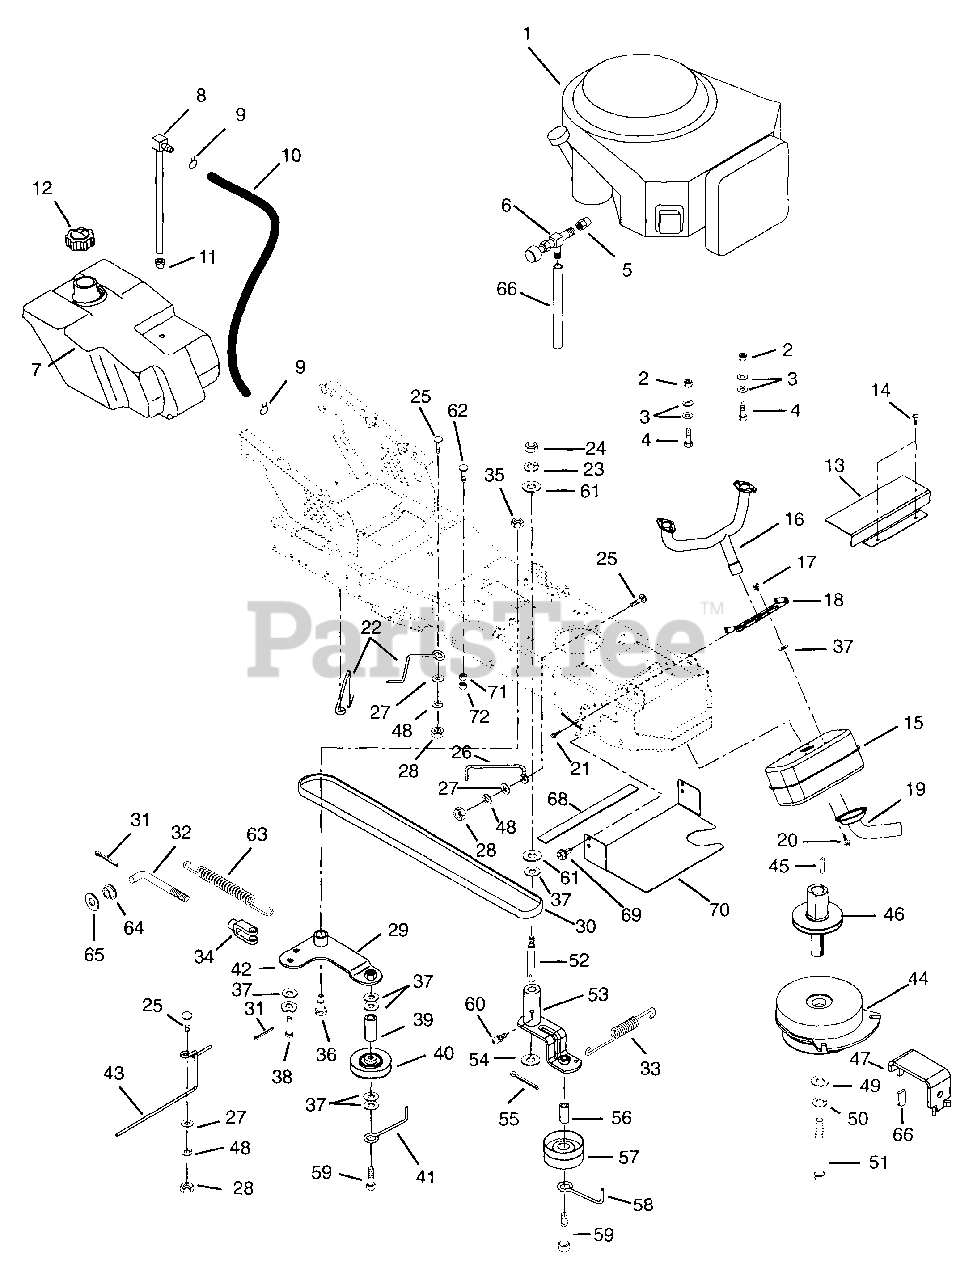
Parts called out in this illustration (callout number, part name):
1	18 HP B&S V-TWIN UT
2	@NUT-LK-CTR .31-18 YWZC
3	WSHR-FL-STL .328X.875X.062YWZC
4	@BLT-HEX .31-18X1.50 GR5 YWZC
5	ADAPTER, OIL DRAIN
6	COCK, OIL DRAIN
7	FUEL TANK
8	TANK FITTING
9	CLAMP-HOSE WIR.490/.510X.092#8
10	HOSE- FUEL LINE 48.00"
11	BSHG-FLG .375 X 1.062 X .625 R
12	FUEL CAP
13	SHIELD - HEAT
14	@SCR-TAP .31-18X.50 HWH TR YWZ
15	MUFFLER - EXHAUST
16	PIPE - EXHAUST TWIN B&S
17	@SCR-TAP 12-24X.75 HWH YWZC
18	BRACKET - MUFFLER
19	DEFLECTOR - EXHAUST
20	SCR-TAP 8-32X.38 SL HWH YWZC
21	SCR-TAP .312-18X.50 HWH TR BL
22	BELT FINGER
23	@WSHR-LK .38X.094 REG YWZC
24	@NUT-HEX .38-16 YWZC
25	BLT-RDHDSQSHK.31-18X.75 GR2 YW
26	BELT FINGER
27	@WSHR-FL-STL.344X.688X.065YWZC
28	@NUT-HEX .31-18 YWZC
29	IDLER PIVOT ARM
30	V-BELT, 3L-RAW EDGE
31	@PIN-CTR .09X.75 EXTPRSQCT YWZ
33	SPRING, EXT
34	YOKE, .312-24 X 2.25
35	@NUT-LK-CTR .38-16 YWZC
36	BLT-SHLDR .38-16X1.25
37	WSHR-FL-STL .390X.75X.125 YWZC
38	PIN-CLEV .312X.822 HDND PL
39	TUBE .380 X .625 X 1.360
40	IDLER-V 3X.38
41	FINGER - BELT
42	WAVE WASHER .531X.781X.125FH
43	BELT FINGER - CENTER
44	CLUTCH, ELECTRIC - WARNER
45	KEY-SQ .25 X 1.25 X .25 SAE
46	SHAFT, SHEAVE EXT.
47	ANCHOR- CLUTCH
48	WSHR-LK .312X.097 HVY YWZC
49	WSHR-FL-STL.463X1.375X.25 YWZC
50	WSHR-LK .438X.133 HVY YWZC
51	BLT-HEX .44-20X5.50 GR5 YWZC
52	SHOULDER STUD
53	ARM - IDLER PIVOT
54	WSHR-FL-STL .52X.827X.062 YWZC
55	@PIN-CTR .18X1.25 EXTPRSQCT YZ
56	TUBE .380 X .625 X 1.620
57	IDLER-FLAT 3.25 X .38 NWHAMSHR
58	FINGER - BELT
59	@BLT-HEX .38-16X3.50 GR5 YWZC
60	FTG-LUBE .25-28X.256 YWZC
61	@WSHR-FL-STL.438X1.00X.083 YWZ
62	BLT-RDHDSQNK .31-18X1.0 SHTYZ
63	SG-TENS .105X.85X5.00 WLD 40
64	BSHG-FLG .320X.620X.312 NY
65	WSHR-FL-STL .505X.880X.072 YWZ
66	TUBE OIL DRAIN
67	GRIP .062 X .375 X 1.000 RE
68	HEAT SHIELD- FABRIC 1X10.75
69	@SCR-TAP 12-24X.75 HWH YWZC
70	SHIELD - HEAT
71	NUT-LK-NYL.312-18 PL
72	@NUT-LK-CTR .31-18 YWZC
